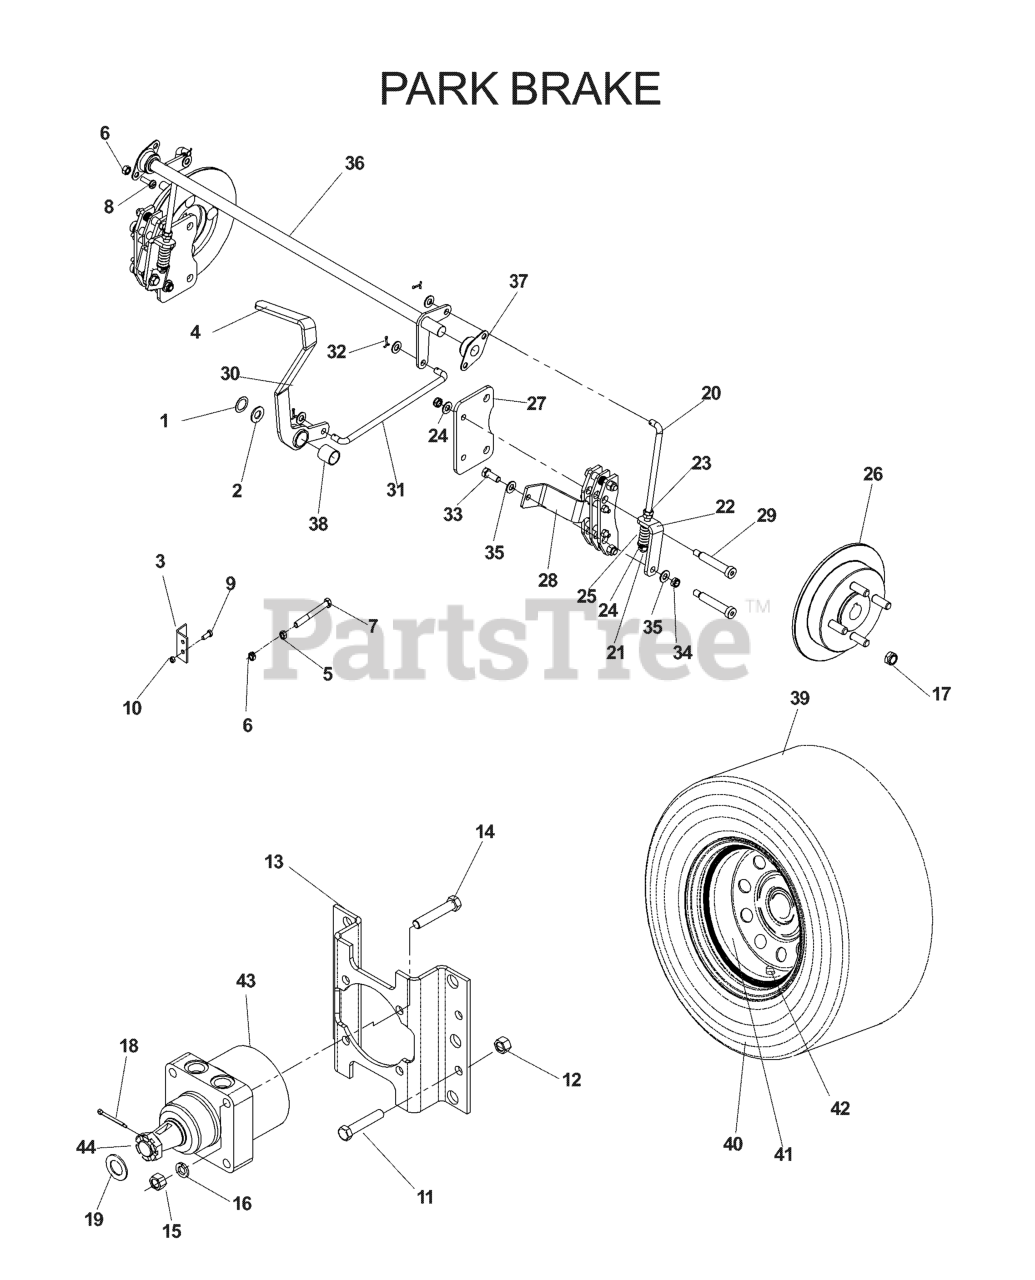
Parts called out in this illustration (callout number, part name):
1	RETAINING RING, 7/8"
2	BSHG .875 X 1.375 X .074 ZD
4	GRIP, PARK BRAKE
5	NUT 3/8C WHIZ
6	NUT 3/8-16 NYLOC
7	HCS 3/8C X 2 1/2
8	HCS 3/8-16X1.GRD.5.ZD
9	HCS 1/4C X 3/4 HCS
10	NUT.1/4-20.HEX.NYLOC.ZD
11	HCS 1/2C X 1 1/4 SERRATED HEAD
12	NUT 1/2-13 HEX NYLOC ZD
13	MOTOR STANDOFF
14	HCS 1/2C X 2 3/4
15	NUT HEX 1/2
16	WASHER 1/2" SPLIT LOCK
17	LUG NUT 1/2F
18	PIN COTTER 4MM X 45MM
19	MACHINE BUSHING
20	LINKAGE, REAR BRAKE
21	NUT 3/8F CENTERLOCK
22	BRACKET, L
23	NUT 3/8-24 JAM
24	WASHER 3/8 SAE FLAT
27	PLATE, BRAKE
28	CALIPER ASSEMBLY
29	SB 3/8-16 X 2-1-1/2 SKT HDD ZD
30	BRAKE LEVER WLDMT
31	LINKAGE, BRAKE
32	COTTER PIN 3/32 X 3/4
33	HCS 3/8-16X1.GRD.5.ZD
34	NUT HEX 3/8-16 NYLON, THIN
35	WASHER 3/8 SAE FLAT
36	BRAKE CROSS SHAFT
37	FLANGE BEARING
39	WHEEL/TIRE.ASM.23X9.5-12.GREY
40	TIRE.TURF.MASTER.23X9.5-12
41	RIM.12X7.GRAY.+1".OFFSET.ZTR
42	VALVE STEM TR-412
43	10CC PUMP W/RTN'S
44	NUT 3/4-16 HEX SLTD GR5 ZD
